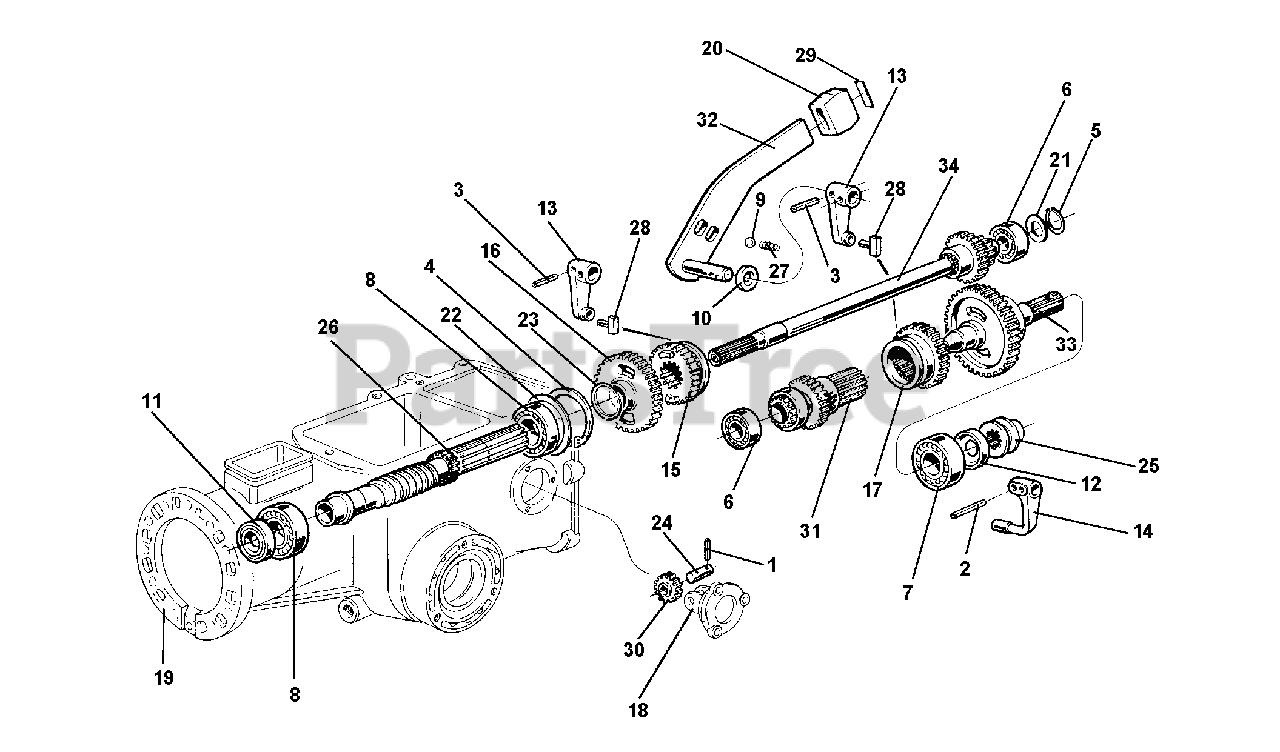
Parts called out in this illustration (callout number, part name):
1	PIN, LOCKING 2.5 X 22 DIN 1481
2	LOCKING PIN 4 X 20 SPIRAL
3	LOCKING PIN 4 X 24 SPIRAL
4	CIRCLIP, INTERN D 52
6	BEARING 15 X 35 X 11 6202
7	BEARING 20 X 47 X 14 6204
8	BEARING SKF 25 X 52 X 15 6205
9	BALL 15/32 RIV RB-11.906
10	SEAL, OIL 12 X 19 X 5 STANDARD
11	SEAL, OIL 15 X 40 X 10 STANDARD
12	SEAL, OIL 20 X 35 X 7 STANDARD
13	LEVER, SPEED CHG SLDG GR
14	SLIDE LEVER
15	SLIDER SPEEDS
16	WHEELS FIRST SPEED
17	REDUCTION UNIT SLIDER
18	FLANGE, REVERSE SPEED
19	CASING 5 SPEEDS GEARBOX
20	KNOB REDUCTION UNIT LEVER
21	WASHER 15.1 X 25 X 2
22	RING C - 72
23	WASHER 25 X 32 X 2 C - 72
29	PLATE SLOW/FAST SPEEDS
30	REVERSE SPEED GEAR
31	GEAR TRIPLE
32	LEVER REDUCTION UNIT
33	P.T.O. SHAFT
34	CLUTCH SHAFT
